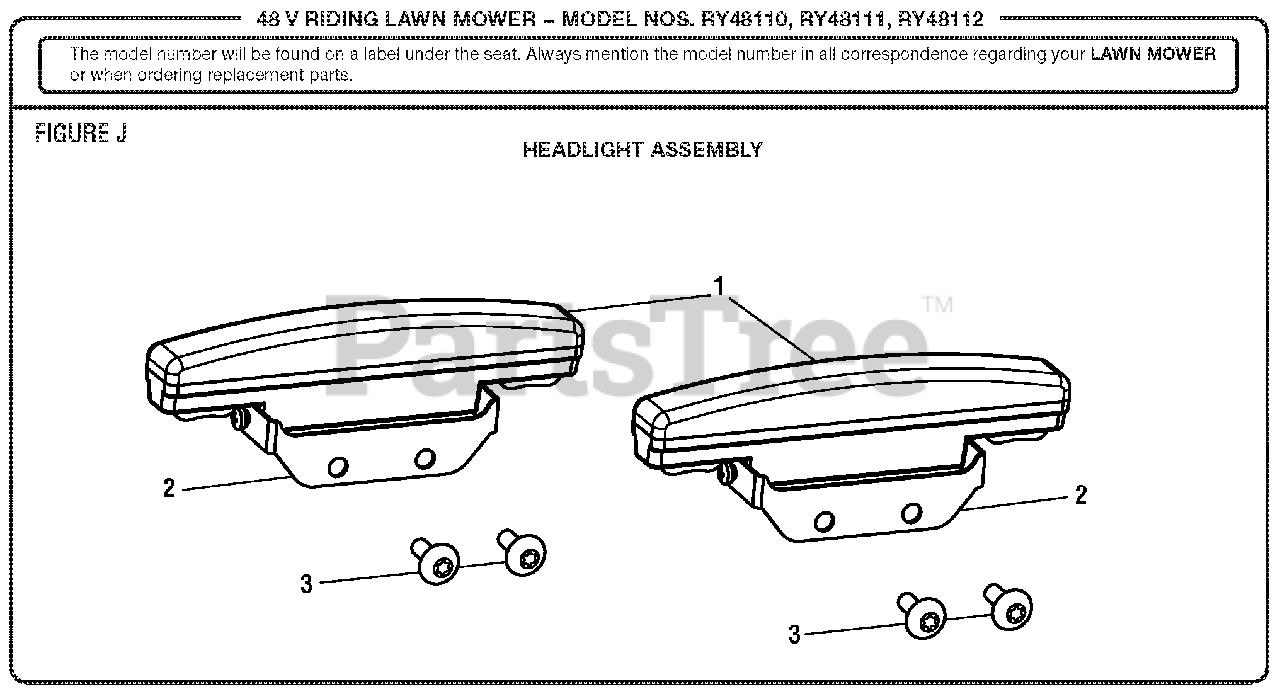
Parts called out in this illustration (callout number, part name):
1	Light Assembly
2	Bracket (Bracket Only)
3	Screw (M6 x 16, Torx. Pan Hd.)
